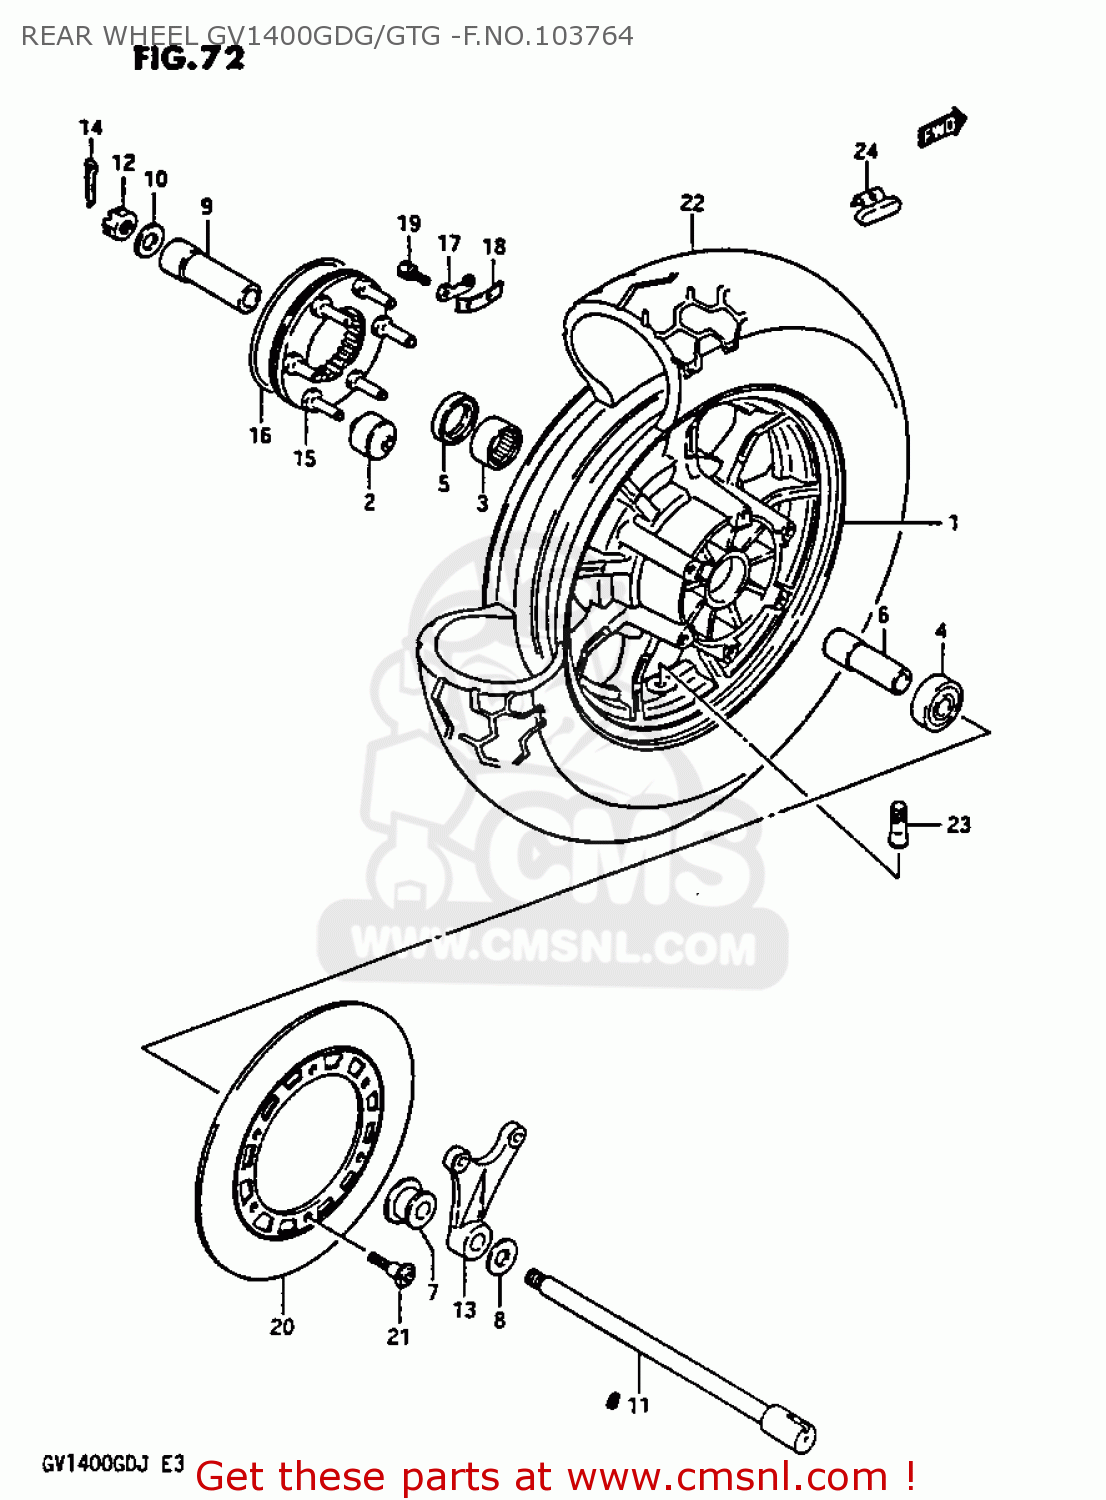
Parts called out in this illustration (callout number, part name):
1	WHEEL SET,REAR (3.50-15)
2	BUSH
3	ROLLER BEARING (30X37X2
4	BEARING
5	SEAL,OIL(30X44X7)
6	SPACER,REAR HUB BEARING
7	SPACER COMP,REAR AXLE
8	WASHER,REAR AXLE,RIGHT
9	SPACER,REAR AXLE,LEFT
10	WASHER,HUB
11	AXLE,REAR
12	NUT 18MM
13	BRACKET,REAR CALIPER
14	PIN,COTTER
15	JOINT ASSY,RR HUB DRIVEN
16	O RING(D:2.1,ID:65)
17	WASHER
18	WASHER,THRUST(T:1.6)
19	BOLT(6X16)
20	DISC,RR BRAKE
21	BOLT
22	TIRE 150/90-15 (T/L)
23	VALVE ASSY,WHEEL RIM(TR412)
24	BALANCER,WHEEL
